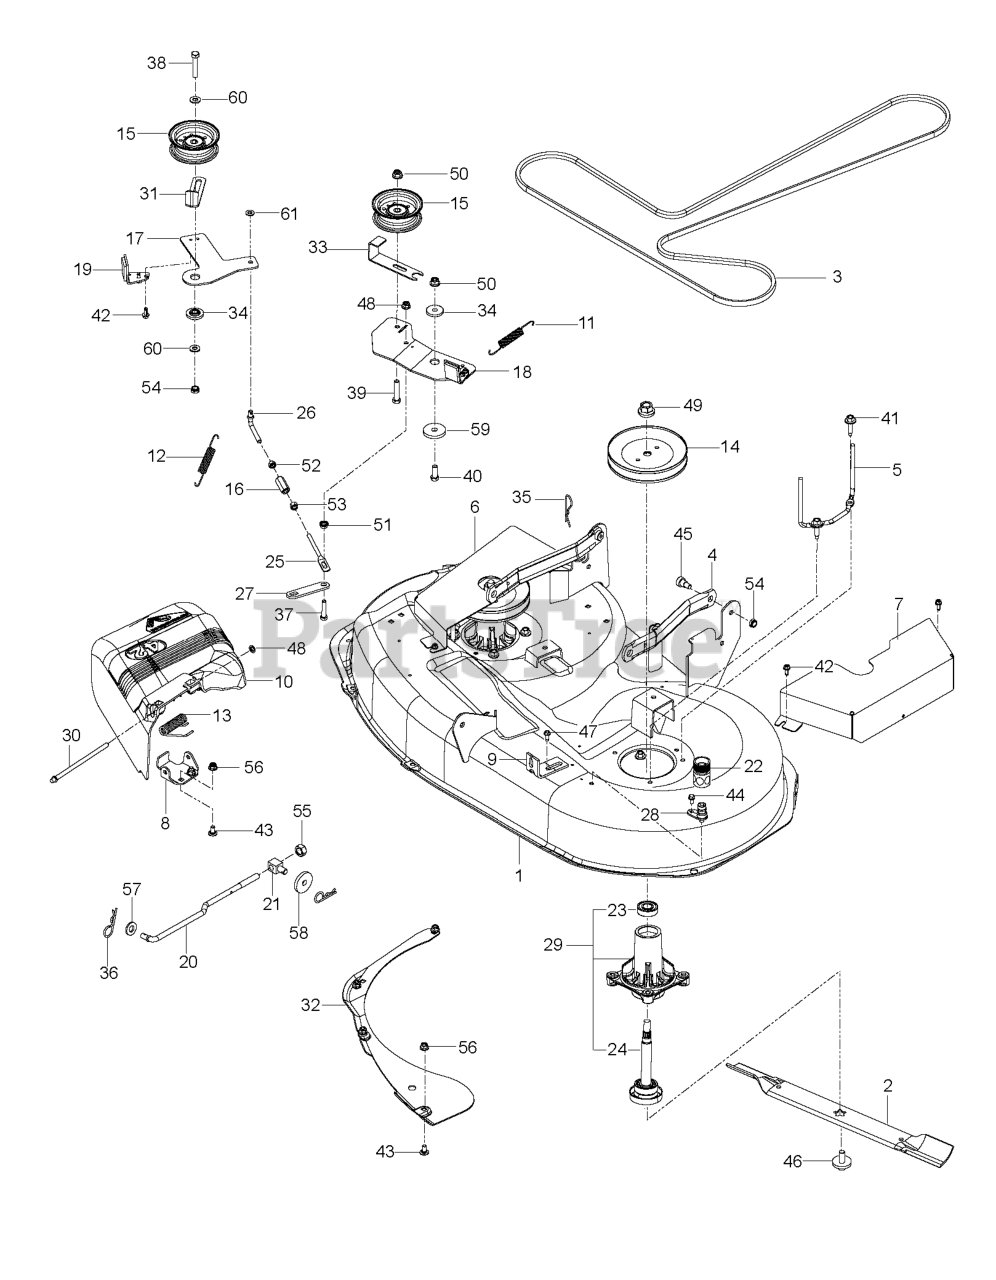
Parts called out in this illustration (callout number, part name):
1	DECK.SVC W/DECALS 42" HTC RZ
2	BLADE.42".MULCH
3	BELT.42.SZ.117.3
4	ARM.SUSPENSION.MOWER
5	BELT KEEPER.MANDREL.38"COATED
6	GUARD.RIGHT.BELT.42"BLACK
7	GUARD.LEFT.BELT.42" BLACK
8	BRKT.DEFLECTOR.38"2005+
9	BRACKET.CLUTCH.CABLE
10	DEFLECTOR 42
11	SPRING RETURN
12	SPRING BRAKE RETURN 42 SZ
13	SPRING TORSION
14	PULLEY.MANDREL.5.438.P
15	PULLEY.IDLER.FLAT
16	ROD END COUPLER
17	ARM.BRAKE.42.BLACK
18	ARM.IDLER.BLACK
19	RP ARM.BRAKE.MOWER.38"LH.TEX
20	LINK LIFT SUSP. FRONT MOWER
21	SWIVEL.TRUNION.LINK.DECK.FRONT
22	COUPLING.QUICK CONNECT
23	BEARING.MANDREL.TOP.EXTENDED
24	SHAFT ASM.MNDRL.N/GREASEABLE
26	LINK SZ42 ADJ, PINNED END
27	PLATE.ATTACHMENT.CLUTCH.(2 2)
28	PORT.WASHOUT
29	MANDREL.NONGREASEABLE.TALL
30	ROD.HINGE
31	GUIDE, BELT
32	BAFFLE VORTEX 42
33	KEEPER, BELT
34	SPACER.RETAINER
35	SPRING.RETAINER.YELLOW.ZINC
36	HAIRPIN #4
37	CAPSCREW 5/16 X 1/1/2 HEX HEAD
38	CAP.SCREW.HEX.HD.3/8-16
39	BOLT
41	BOLT.HEX.WASHR.HED.313-18X1.19
42	SCREW- 1/4-20 X 5/8
43	BOLT.CARR.5/16-18X5/8.SHORT
44	SCREW.1/4-20X5/8
45	SB 3/8-16 X 3/8 SKT HD ZD
46	SCREW.SEMS.7/16-20X1.HEX.HEAD
47	BOLT.5/16HEX.WHS.HD
48	NUT PUSH M
49	LOCKNUT - 9/16
50	NUT 3/8-16 HEX FLG NYLOC ZD
51	NUT 5/16C WHIZ
52	NUT 5/16F LEFTHAND
54	NUT HEX 3/8-16 NYLON, THIN
55	NUT, 7/16-20 HEX NYLOC ZC
56	5/16-18 NYLOC FLANGE NUT
57	WASHER STEEL
58	SPINDLE WASHER
59	WASHER, FRICTION
60	WASHER
61	WASHER
